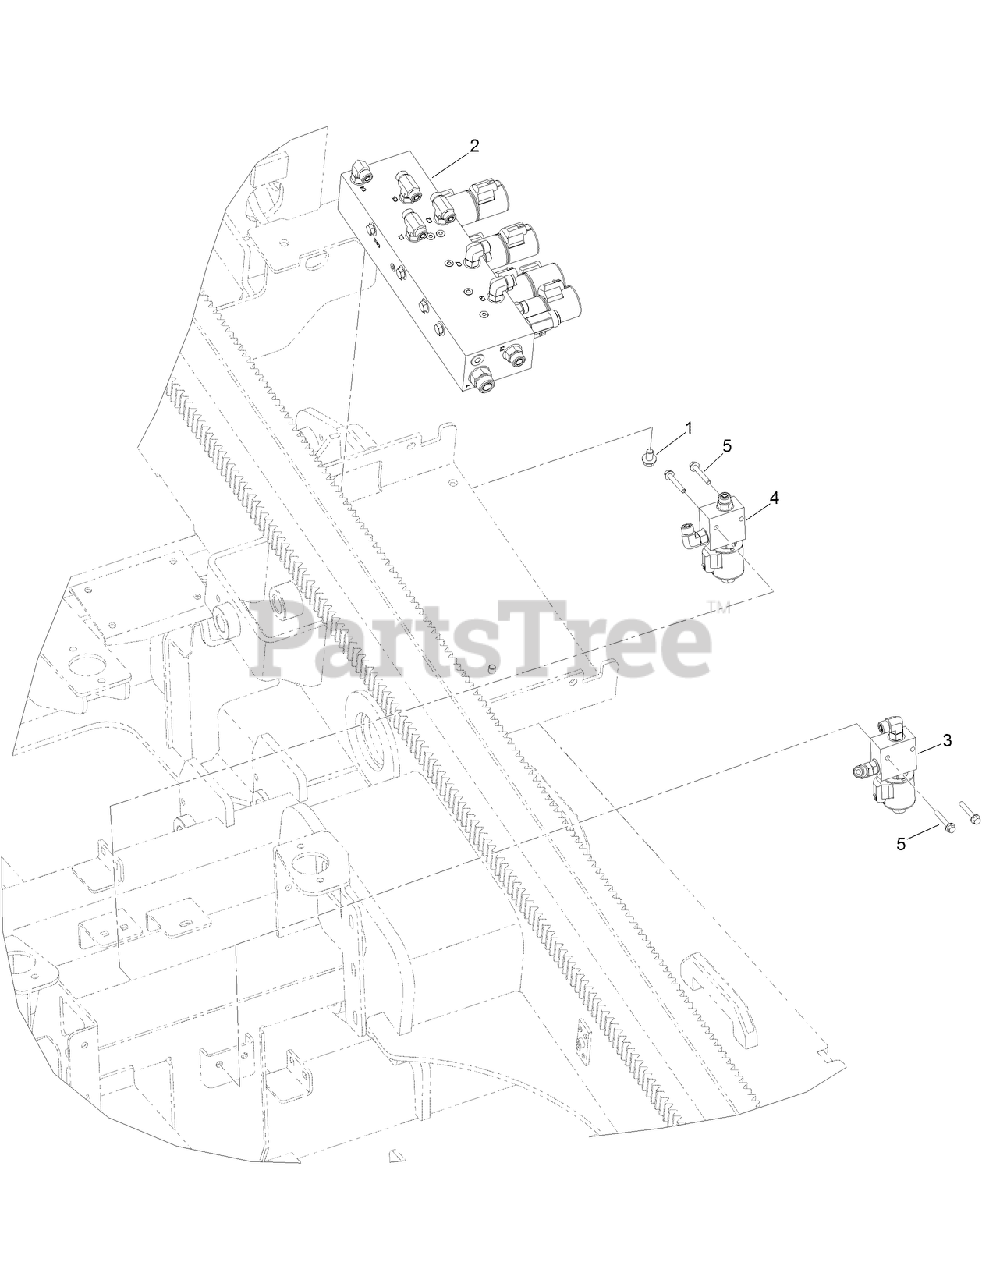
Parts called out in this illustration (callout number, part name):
1	SCREW-HHF
2	LOADING MANIFOLD ASM
3	FRONT PROPORTIONAL RELIEF MANIFOLD ASM
4	REAR PROPORTIONAL RELIEF MANIFOLD ASM
5	SCREW-HHF
